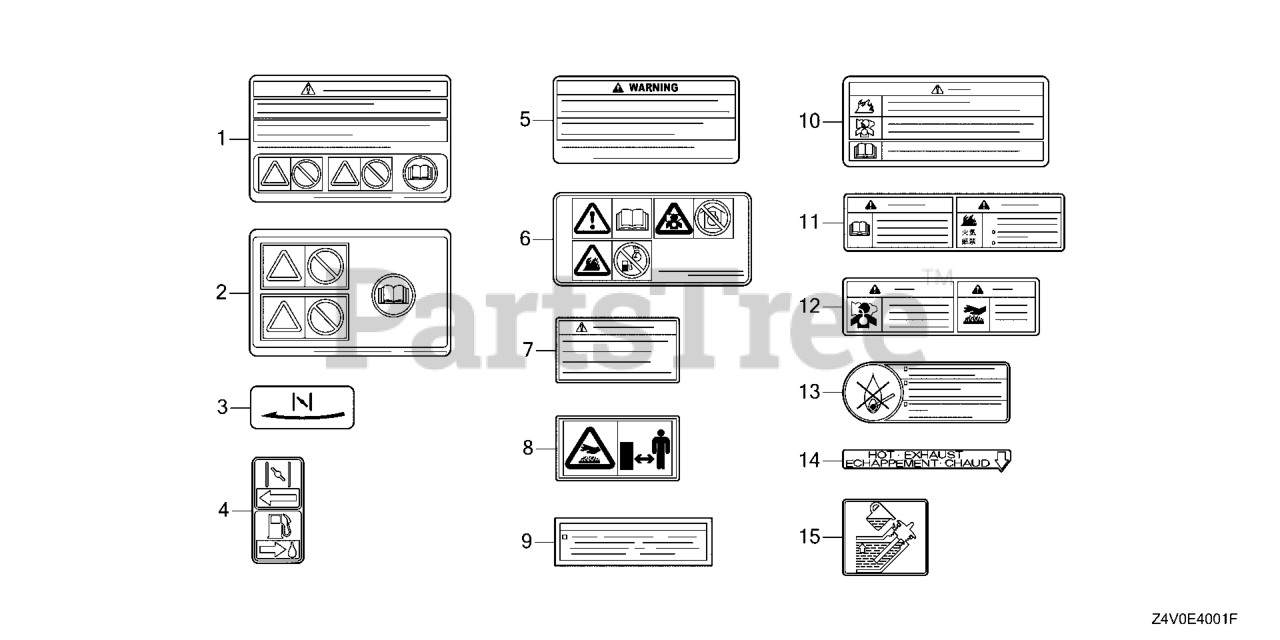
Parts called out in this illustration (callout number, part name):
5	MARK, OPERATOR CAUTION (FRENCH)(MADE IN THAI)
6	MARK, OPERATOR CAUTION (PICTOGRAPH)
7	MARK, EX. CAUTION (FRENCH)
8	MARK, EX. CAUTION (PICTOGRAPH)
10	MARK, OPERATOR CAUTION (CHINESE)
